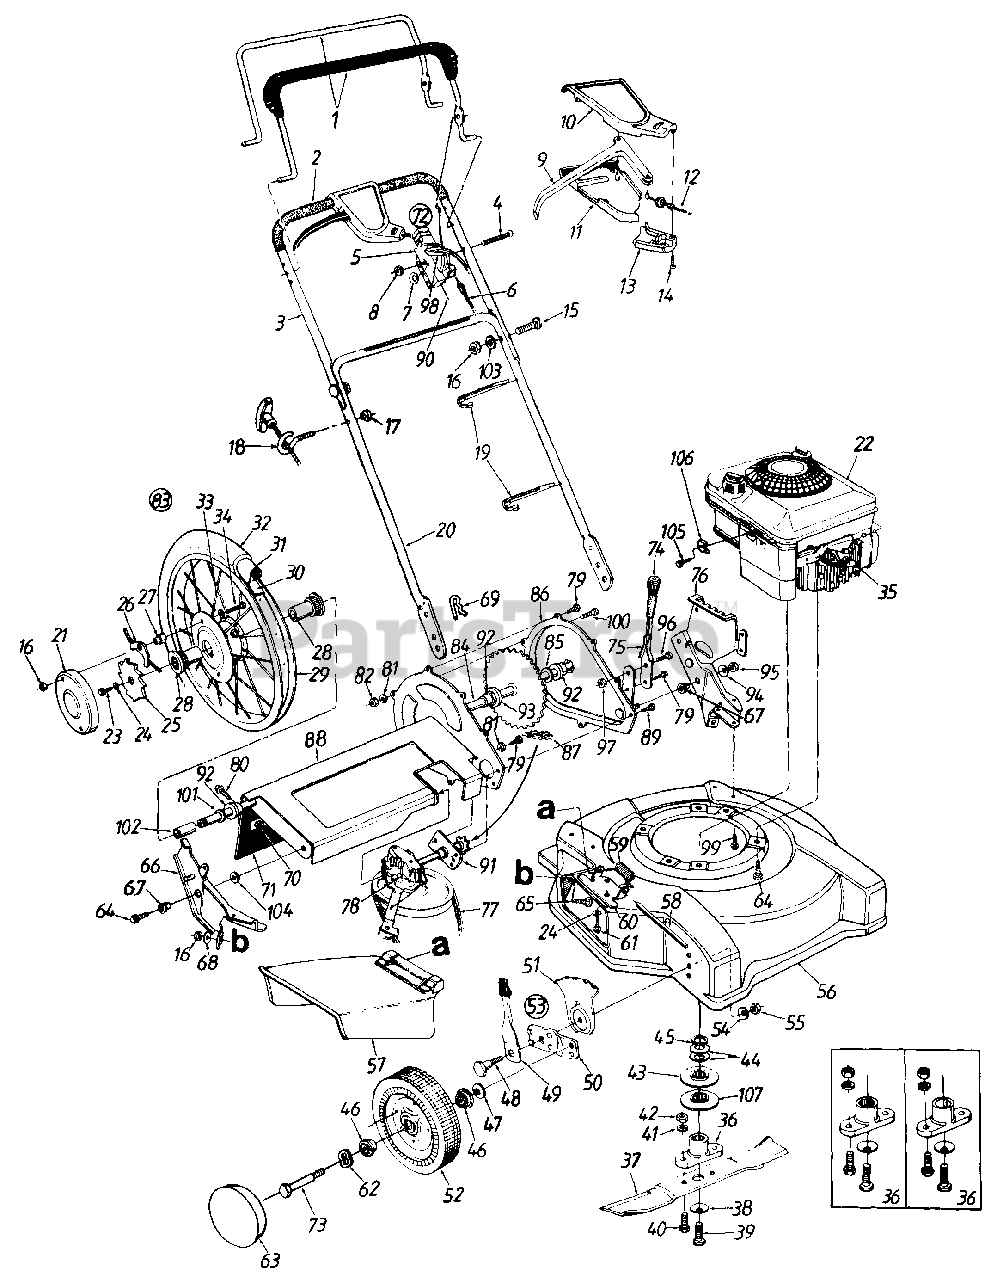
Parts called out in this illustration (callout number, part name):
1	Control Handle Ass'y.
2	Foam Grip
4	Oval C-Sunk Scr.
5	Throttle Body
6	Control Cable - 39" Lg.
7	Spring Wash. .66" I.D.
8	Hex L-Nut 1/4-20 Thd.
9	Control Lever
10	Control Cover Half - Upper
11	Control Cover Half - Lower
12	Self-Propelled Cable - 48" Lg.
13	Cable Mounting Cap
14	Fl-"C" Sunk Hd. Tap Scr. #10 x .75" Lg.
15	Curved Carr. Bolt 5/16-18 x 1.38" Lg.
16	Hex Nut 5/16-18 Thd.
17	Hex L-Nut 1/4-20 Thd.
19	Cable Tie
20	Lower Handle
21	Wheel Cover
22	Engine
23	Hex Bolt 1/4-20 x .75" Lg. (Gr. 5)
24	Bell-Wash. 1/4" I.D.
25	Wheel Ratchet
26	Pawl and Spring Ass'y.
27	Special Hex Nut 5/16-18 Thd.
28	Flange Bearing .63" I.D.
29	Rim Ass'y. Only 16" x 2.1"
30	Rimstrip 16" x 7/8"
31	Inner Tube 16" x 2.12"
32	Chevron Tire 16" x 2.125"
33	Intern. L-Wash. 5/16" I.D.
34	Hex Bolt 5/16-18 x 1.0" (Gr. 5)
35	Spark Plug Boot
36	Blade Adapter Kit
37	22" Blade
38	Bell-Wash. .39" I.D.
39	Hex Bolt 3/8-24 x 1.5" Lg.
40	Hex Bolt 3/8-24 x 1" Lg.
41	L-Wash. 3/8" I.D.
42	Hex Nut 3/8-24 Thd.
43	Upper Pulley Half
44	Bell-Wash. 7/8" I.D.
45	Crankshaft Spacer
46	Ball Bearing 1/2" I.D.
47	Bell-Wash. .38" I.D.
48	Shld. Bolt .5"
49	Spring Lever Ass'y. w/Knob
51	Height Adj. Plate
52	Wheel Ass'y. Comp.
53	Height Adj. Ass'y. Comp. - L.H.
54	Bell-Wash. .39" I.D. x 1.38"
55	Hex Nut 3/8-16 Thd.
58	Hinge Pin
59	Torsion Spring
60	Adapter Plate
61	Hex TT-Tap Scr. 1/4-20 x .5"
62	Wave Wash. .53" I.D. x .78"
63	Hub Cap
64	Hex TT-Tap Scr. 3/8-16 x 1"
65	Carriage Bolt 5/16-18 x .62" Lg.
66	Handle Brkt. Ass'y. - R.H.
67	Shld. Spacer .5" x .10"
68	Bell-Wash. 5/16" I.D.
69	Intern. Cotter Pin 5/16" Dia.
70	Retaining Strip
72	Throttle Box Comp.
73	Front Axle Bolt
75	Height Adjustment Lever
78	Transmission Comp.
79	Hex B-Tap Scr. 1/4 x .38" Lg.
80	Hex AB-Tap Scr. 1/4 x .62" Lg.
81	L-Wash. 1/4" I.D.
82	Hex Nut 1/4-20 Thd.
83	Wheel Ass'y. Comp.
84	Sprocket and Axle Ass'y.
85	Fl-Wash. .635" I.D. x 1.0" O.D.
90	Throttle Cable
92	Hex Flange Brg. .631" I.D.
93	Spacer .63" I.D. x 1.25"
94	Fl-Wash. .385" I.D. x .87" O.D.
95	Hex L-Nut 3/8-24 Thd.
96	Hex Bolt 3/8-16 x .62" Lg.
97	Flanged L-Nut 3/8-16 Thd.
98	Throttle Lever
99	Hex B-Tap Scr. 5/16-18 x .5"
100	Hex Bolt 1/4-20 x .5" Lg.
101	Fl-Wash. .632" I.D. x .943"
102	Spacer .628" I.D. x .875"
103	L-Wash. 1/4" I.D.
104	Fl-Wash. .38" I.D. x 1" O.D.
105	Hex Wash. Hd. Scr. #10-32 x .62" Lg.
106	Casing Clamp
107	Lower Pulley Half
